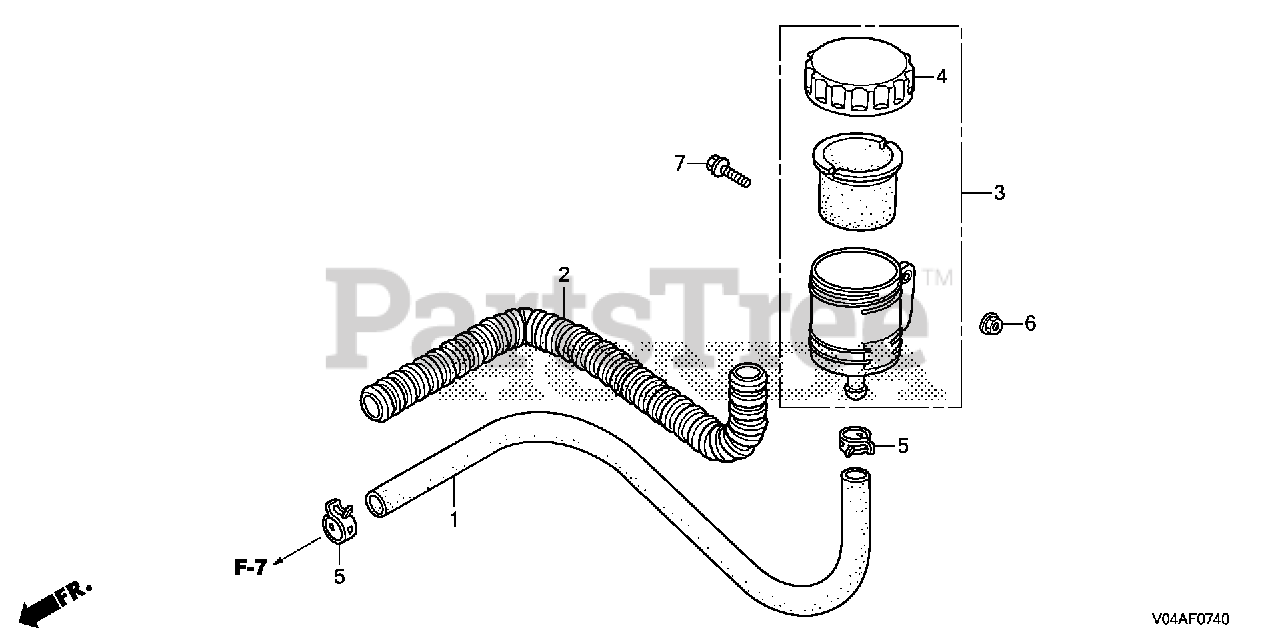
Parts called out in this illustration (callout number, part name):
2	PROTECTOR, OIL TUBE
3	TANK ASSY., OIL
4	BODY, OIL CAP
5	CLAMP D (19MM)
6	NUT, FLANGE (6MM)
7	BOLT, FLANGE (6X16)
